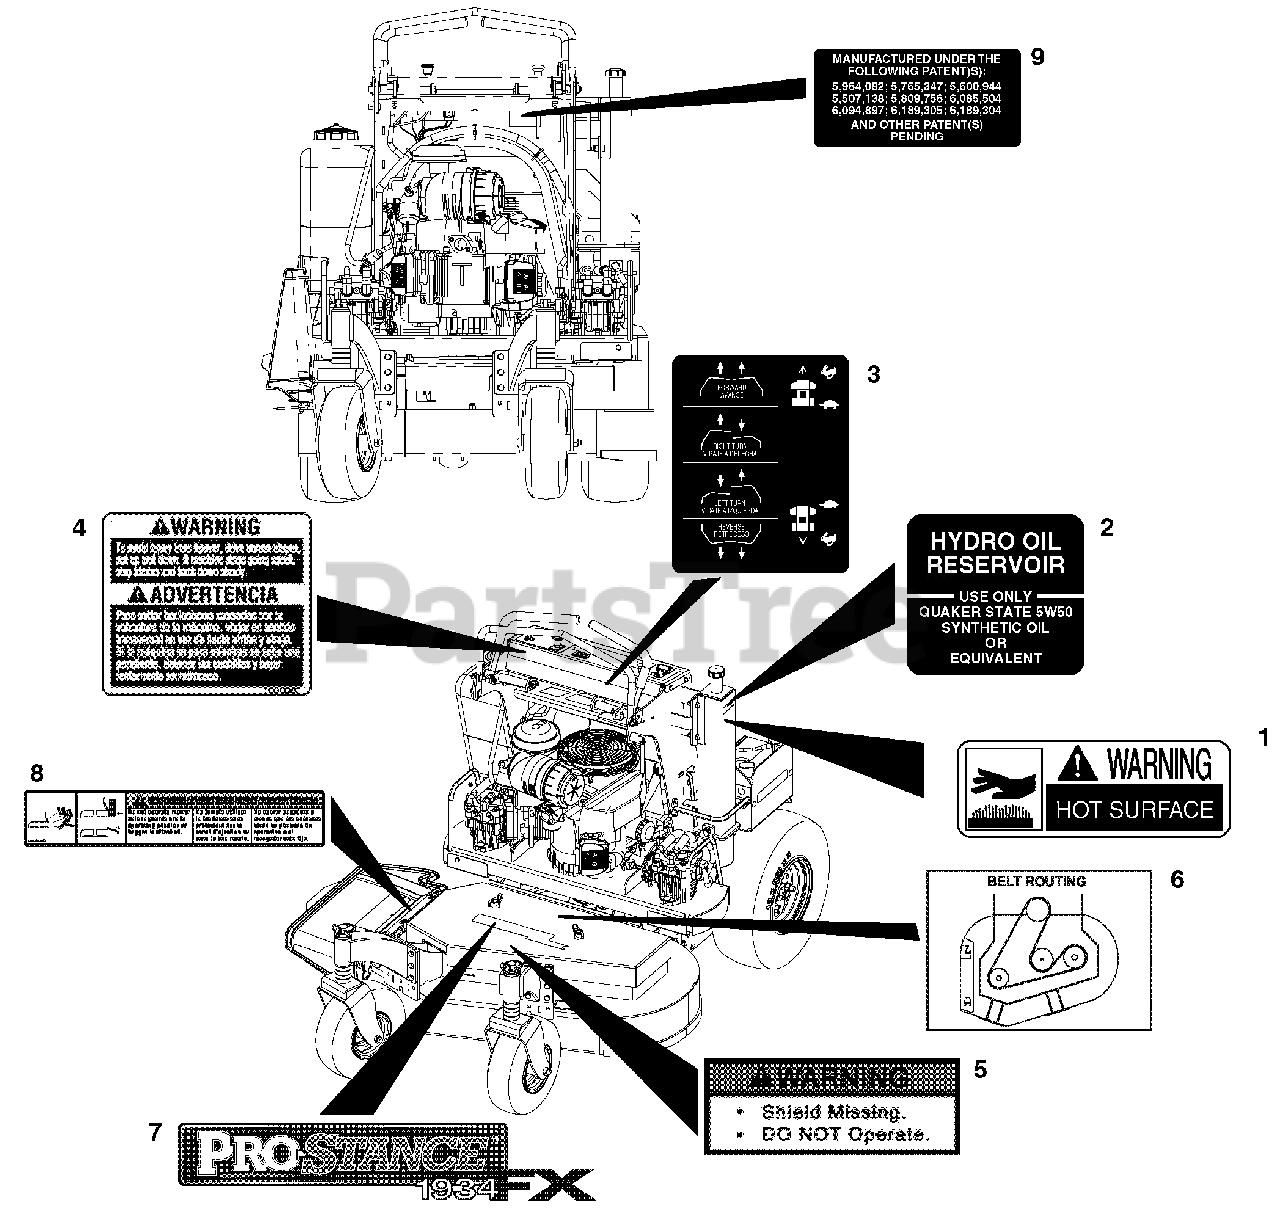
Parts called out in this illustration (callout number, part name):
1	Decal, Warning, Hot Surface
2	Decal, Hydro Oil Reservoir
3	Decal, Directional Control
4	Decal, Danger - Avoid Tipover
5	Decal, Warning, Shield
6	Decal, Belt Path
7	Decal, Pro-Stance 1934FX
8	Decal, Danger - Thrown Objects
9	Decal, Patent
